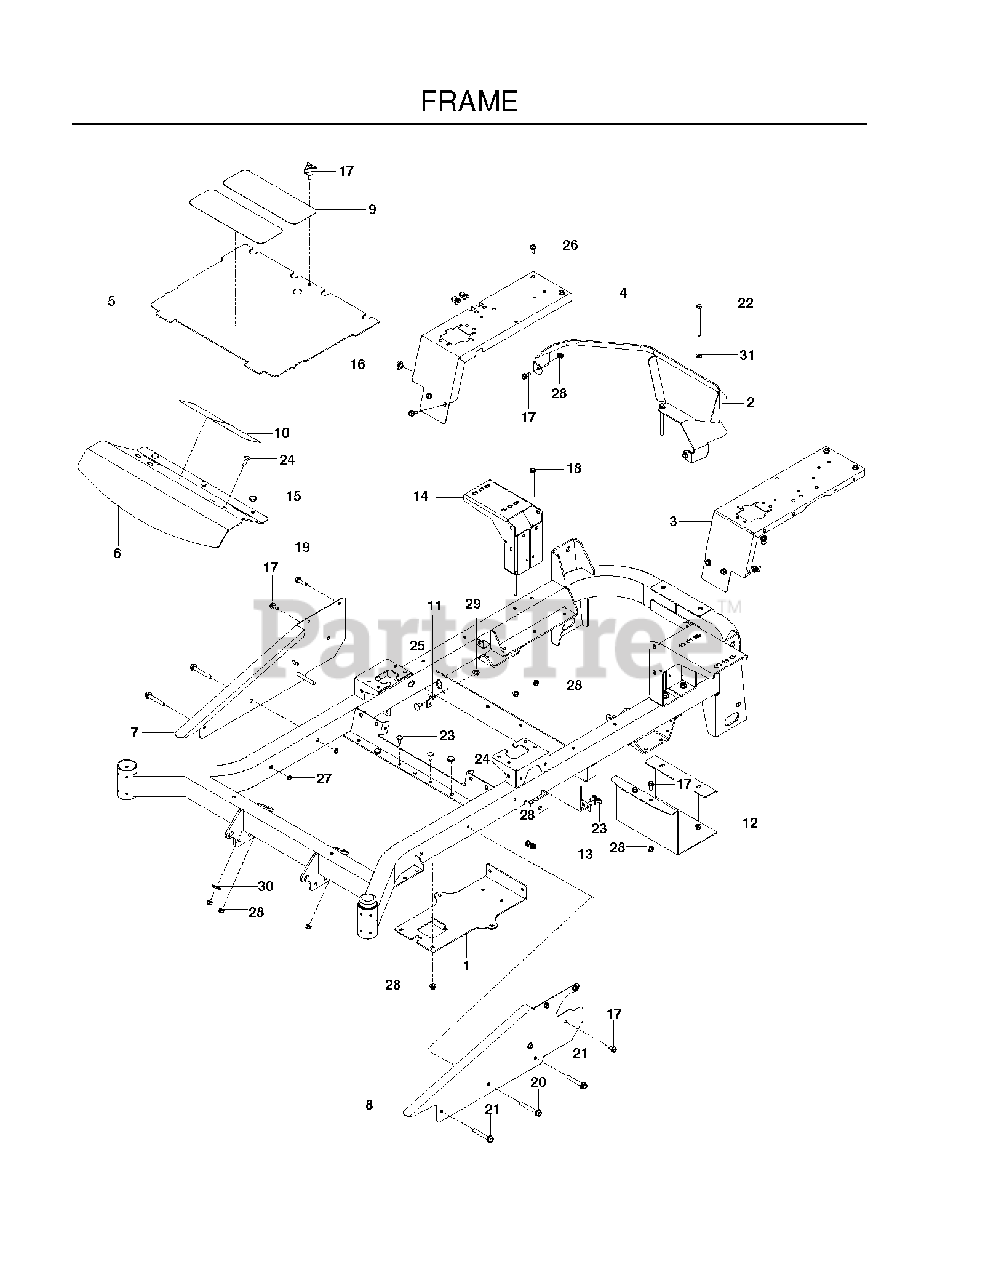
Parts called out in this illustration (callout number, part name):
1	PLATE, BATTERY, BLACK
2	GUARD, REAR MZ, GRAY
3	PANEL.FILLER.LT.ORANGE
4	PANEL.FILLER.RT.ORANGE
5	PLATE, FLOOR W/DECALS
6	PLATE, FOOTREST
7	SIDE.RT.ORANGE
8	SIDE.LT.ORANGE
9	ANTI-SKID PAD
11	BRACKET.DAMPENER.BLACK
12	SHIELD.MUFFLER.BLACK
13	STOP, DECK, EZ+
14	MOUNT, TANK, ZT BLK
15	GROMMET, BUMPER
16	U-CLIP 5/16-18 NUT RETAINER
17	HHFS 5/16-18 X 3/4
18	HHFS 5/16-18 X 3 3/4
19	HHFS 5/16-18 X 1.25 TPBLT GD 5
20	HHFS 3/8-16 X 2 3/4
21	HHFS 3/8-16 X 2.5 GR 5 ZD
22	HCS 5/16C X 4
23	BOLT 5/16C X 3/4" CARRIAGE
24	RHSNB 5/16C X 1
25	RHSNB 3/8-16 X 3/4 GR 5 BLK ZN
26	BOLT 5/16-18 X 3/4
27	NUT HEX 3/8-16 NYLON, THIN
28	5/16-18 NYLOC FLANGE NUT
29	NUT 3/8-16 HEX FLG NYLOC ZD
30	WASHER 1/2" FLAT
31	FLAT WASHER 5/16 SAE
